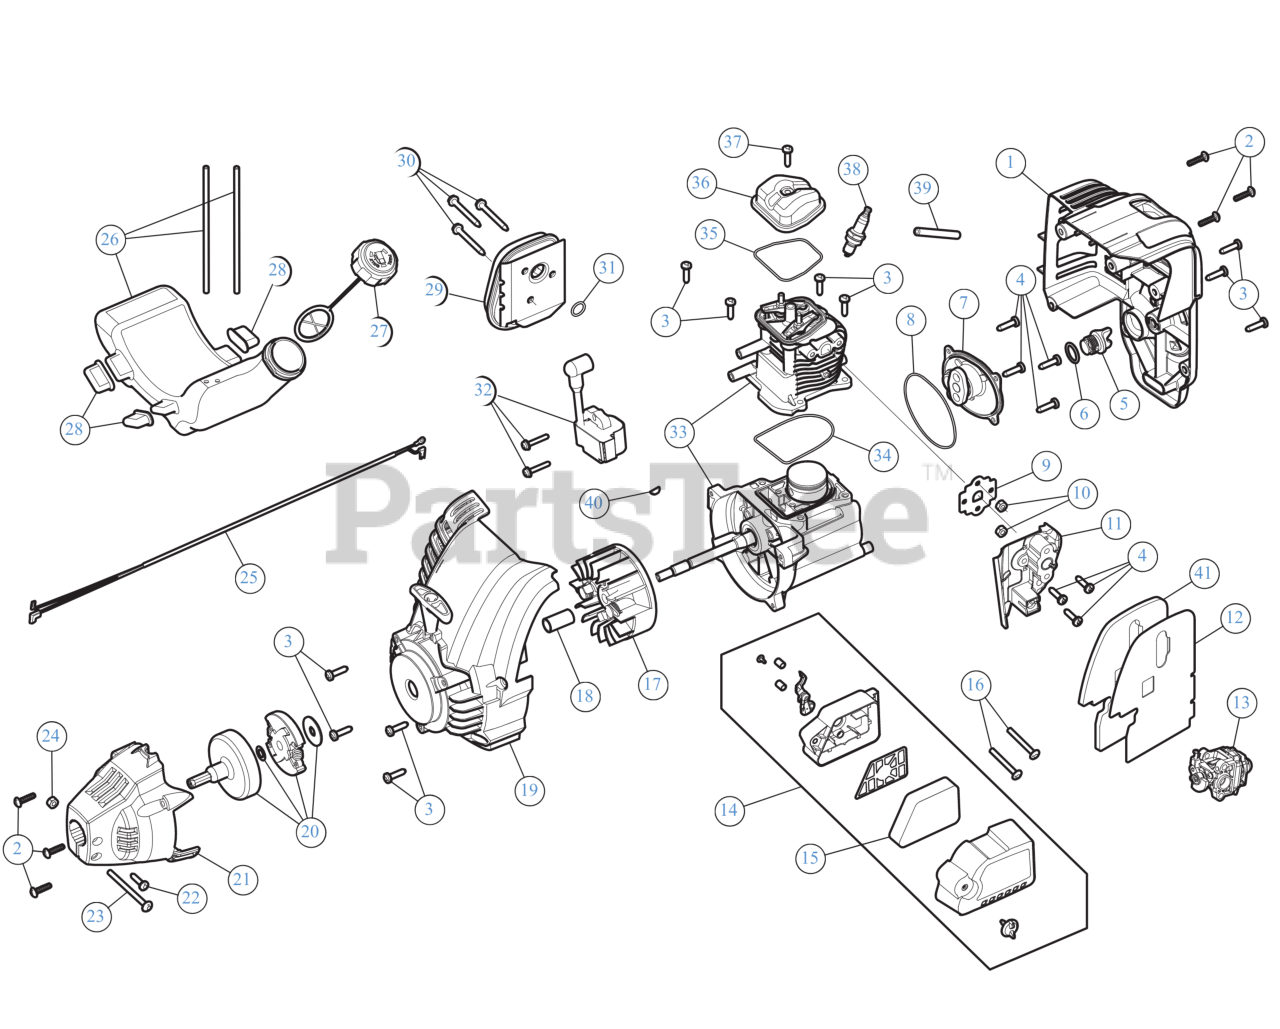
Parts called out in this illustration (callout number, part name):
1	ENGINE COVER ASSEMBLY RR
2	SCREW 8-16 x 3/4
3	SCREW M5-0.8 x 19
4	SCREW, M5 X18
5	OIL PLUG
6	RING, OIL PLUG (AC
7	CRANKCASE COVER
8	O-RING CRNKCSE CVR
9	GASKET/INSULATOR
10	NUT 10-32
11	CARB INSULATOR
12	GASKET
13	CARBURETOR
14	AIR CLEANER COVER
15	AIR FILTER
16	SCREW 10-32X2.5
17	FLYWHEEL ASSEMBLY AC3.1
18	SPACER :2.165"
19	STARTER HOUSING
20	CLUTCH ASSEMBLY
21	CLUTCH COVER ASSEMBLY
22	SCREW 8-18X.375 T-20
23	SCREW
24	HEX NUT
25	WIRE LEAD
26	FUEL TANK ASSEMBLY
27	FUEL CAP ASSEMBLY 43MM-6 W/O HOLE
28	FUEL TANK PADS
29	MUFFLER ASSEMBLY
30	SCREW M5 x 44MM
31	GASKET/MUFFLER
32	MODULE ASSEMBLY
33	SHORT BLOCK
34	O-RING CYL AC5
35	O-RING
36	ROCKER COVER
37	SCR, VALVE COVER
38	SPARK PLUG 4 CYCL
39	BREATHER HOSE
40	WOODRUFF KEY #403-.125 x .375
41	HEAT SHIELD
